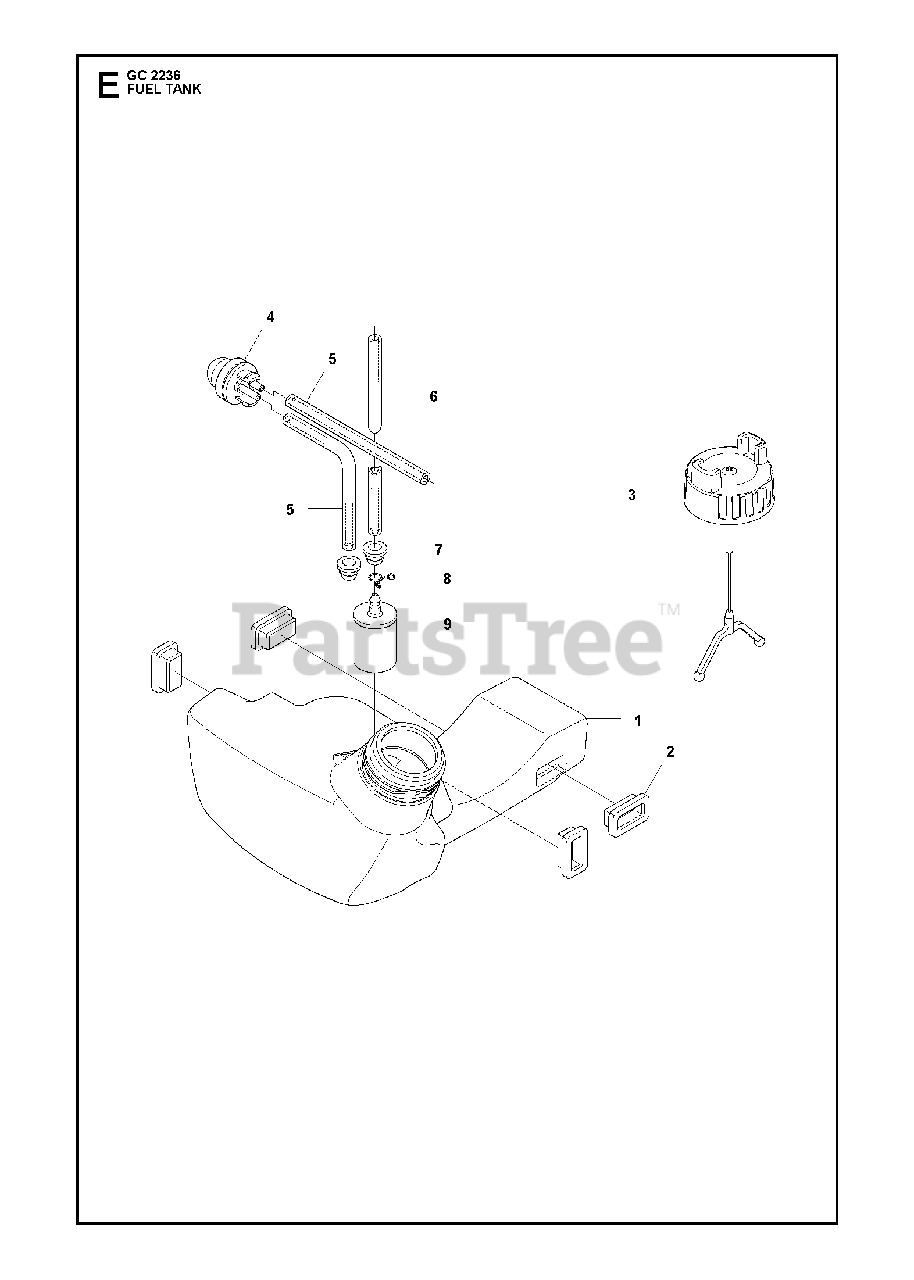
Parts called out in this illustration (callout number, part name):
1	TANK ASSY
3	TANK CAP
4	AIR PURGE BUBBLE
7	FUEL TANK BUSHING
9	FUEL FILTER
